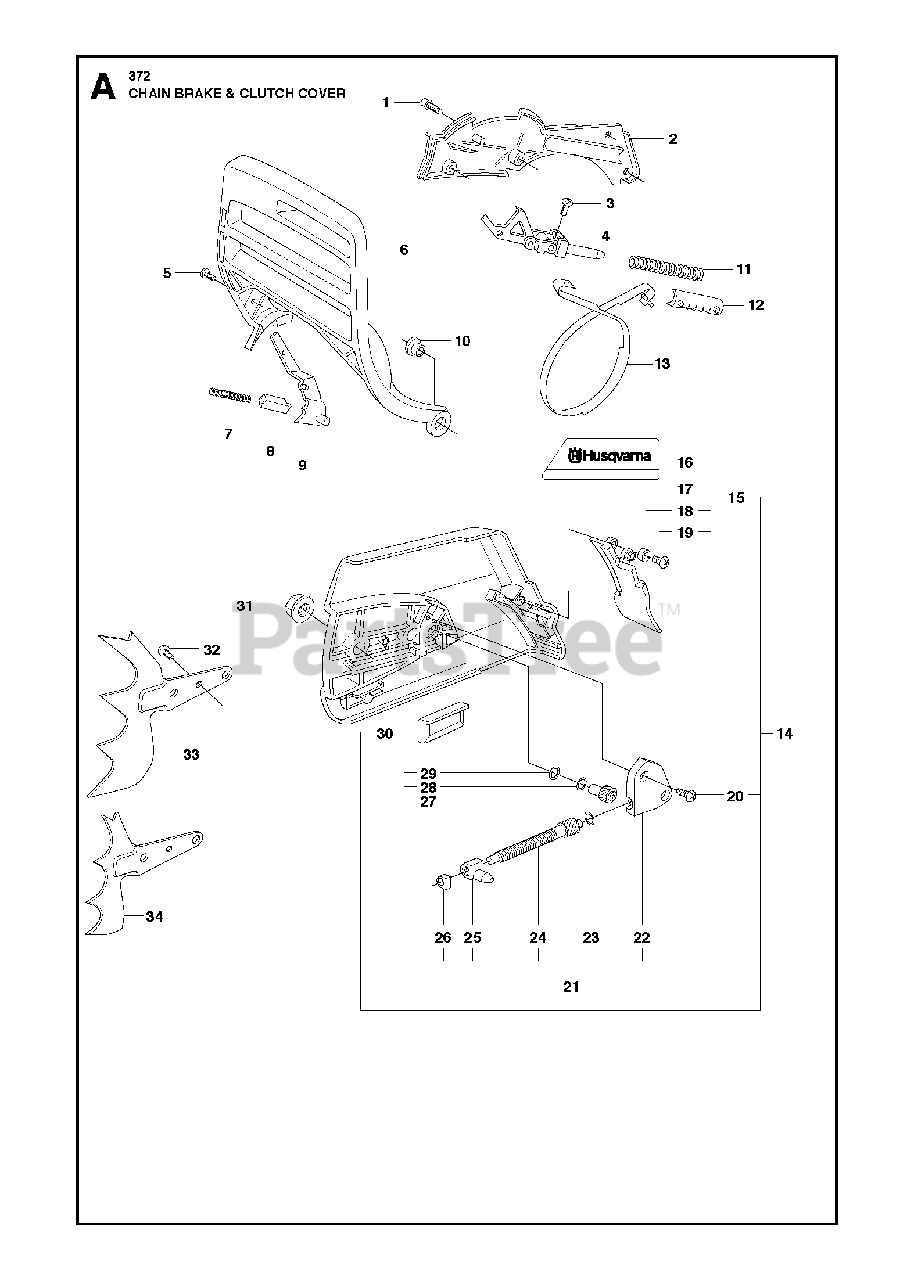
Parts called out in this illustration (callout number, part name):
1	SCREW
7	LOCK SPRING
9	BRAKE LEVER
11	BRAKE SPRING
13	BRAKE BAND
14	CHAIN BRAKE COVER
15	CHAIN BRAKE COVER
16	DECAL
17	PROTECTOR
18	WASHER
19	SCREW
20	SCREW
21	KIT-CHAIN TENSIONER
22	COVER
23	WASHER
24	WORM SCREW / ADJUSTER
25	PAWL
26	SLEEVE
27	WORM WHEEL
28	WASHER
29	O-RING
30	CHAIN GUIDE
31	NUT M8 FLANGE
33	FELLING DOG
34	SPIKE OUTER
